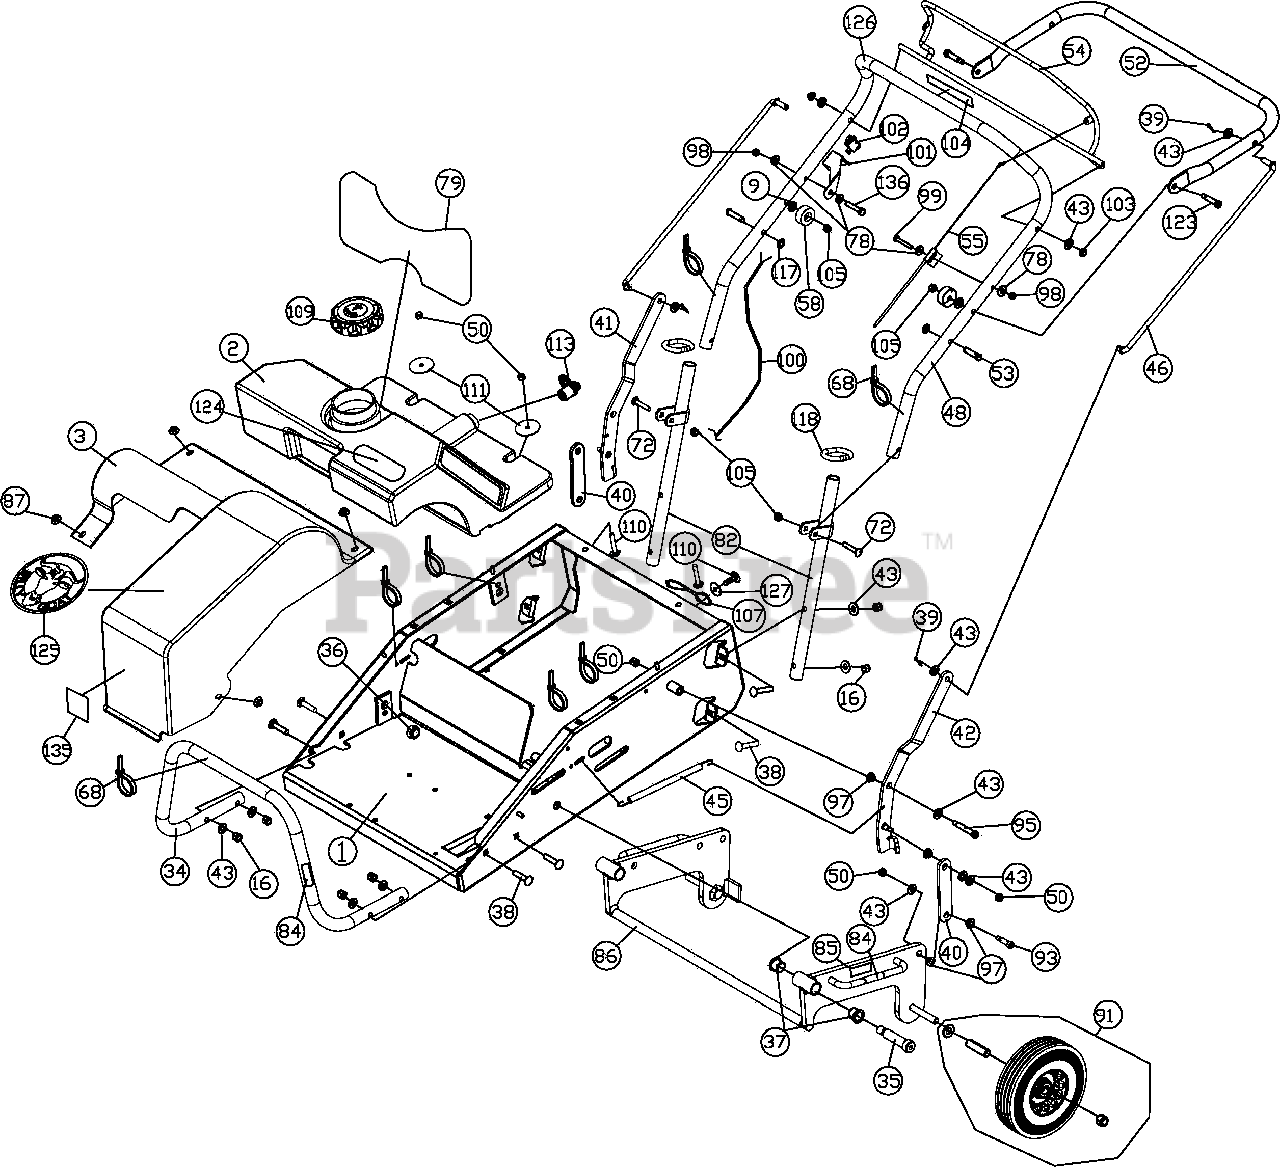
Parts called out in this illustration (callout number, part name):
1	FRAME ASSEMBLY WA AE402
2	WATER TANK 5.5 GAL
3	GUARD DRIVE COVER
9	WASHER 5/16 FENDER
16	NUT LOCK 3/8-16
34	TUBE FRONT BUMPER
35	BOLT SHOULDER 3/4 x 2.5
36	NUT LOCK 5/8-11 THIN
37	BUSHING PIVOT
38	BOLT CARRIAGE 3/8-16 x 1.75"
39	COTTER PIN
40	BRACKET LIFT LINK
41	PLATE LINKAGE LH LONG WA AE
42	PLATE LINKAGE RH LONG WA AE
43	WASHER FLAT 3/8 SAE
45	SPRING EXTENSION
48	HANDLE UPPER AE
50	NUT LOCK 5/16-18
52	HANDLE LIFT
53	CLEVIS PIN 3/8" X 1.625
54	BAIL CLUTCH
55	CABLE CLUTCH ASSY
58	BUMPER RECESS
72	CARRIAGE BOLT 5/16-18X1.75
78	WASHER 1/4 SAE
79	LABEL TANK INSTRUCTIONS AE
82	HANDLE LOWER WA
84	LABEL LIFT HERE
85	LABEL WARNING WEIGHT
86	FRAME REAR WA
87	NUT FLANGE 1/4-20
91	TIRE & WHEEL 8" ASSY
93	BOLT SHOULDER 3/8 x 1"
95	BOLT SHOULDER 3/8 x 2"
97	BUSHING SHOULDER NYLON 3/8 ID
98	NUT LOCK 1/4x 20 THIN
99	SCREW CAP 1/4 - 20 x 1 1/2"
100	HARNESS WIRE AE
101	BRACKET MOUNT SWITCH
102	SWITCH ON-OFF
103	NUT - PAL 3/8
104	CLUTCH LABEL
105	NUT LOCK 5/16 -18 THIN
107	PLASTIC LANYARD
109	CAP WATER TANK
110	SCREW SELF TAP 1/4-20 x 5/8"
111	WASHER - EXTENSION
113	PLUG DRAIN 1"
117	RETAINER 3/8"
118	LOOP FOLDING HANDLE
123	BOLT SHOULDER 3/8 x 1 1/4"
124	LABEL BILLY GOAT OVAL
125	LABEL BILLY GOAT CIRCLE
127	1/4 WASHER FLAT FENDER
135	LABEL MADE IN U.S.A.
136	SCREWCAP 1/4"-20 X 1 1/2" HCS ZP
137	BOLT CARRIAGE 5/16-18 X 2" ZP
